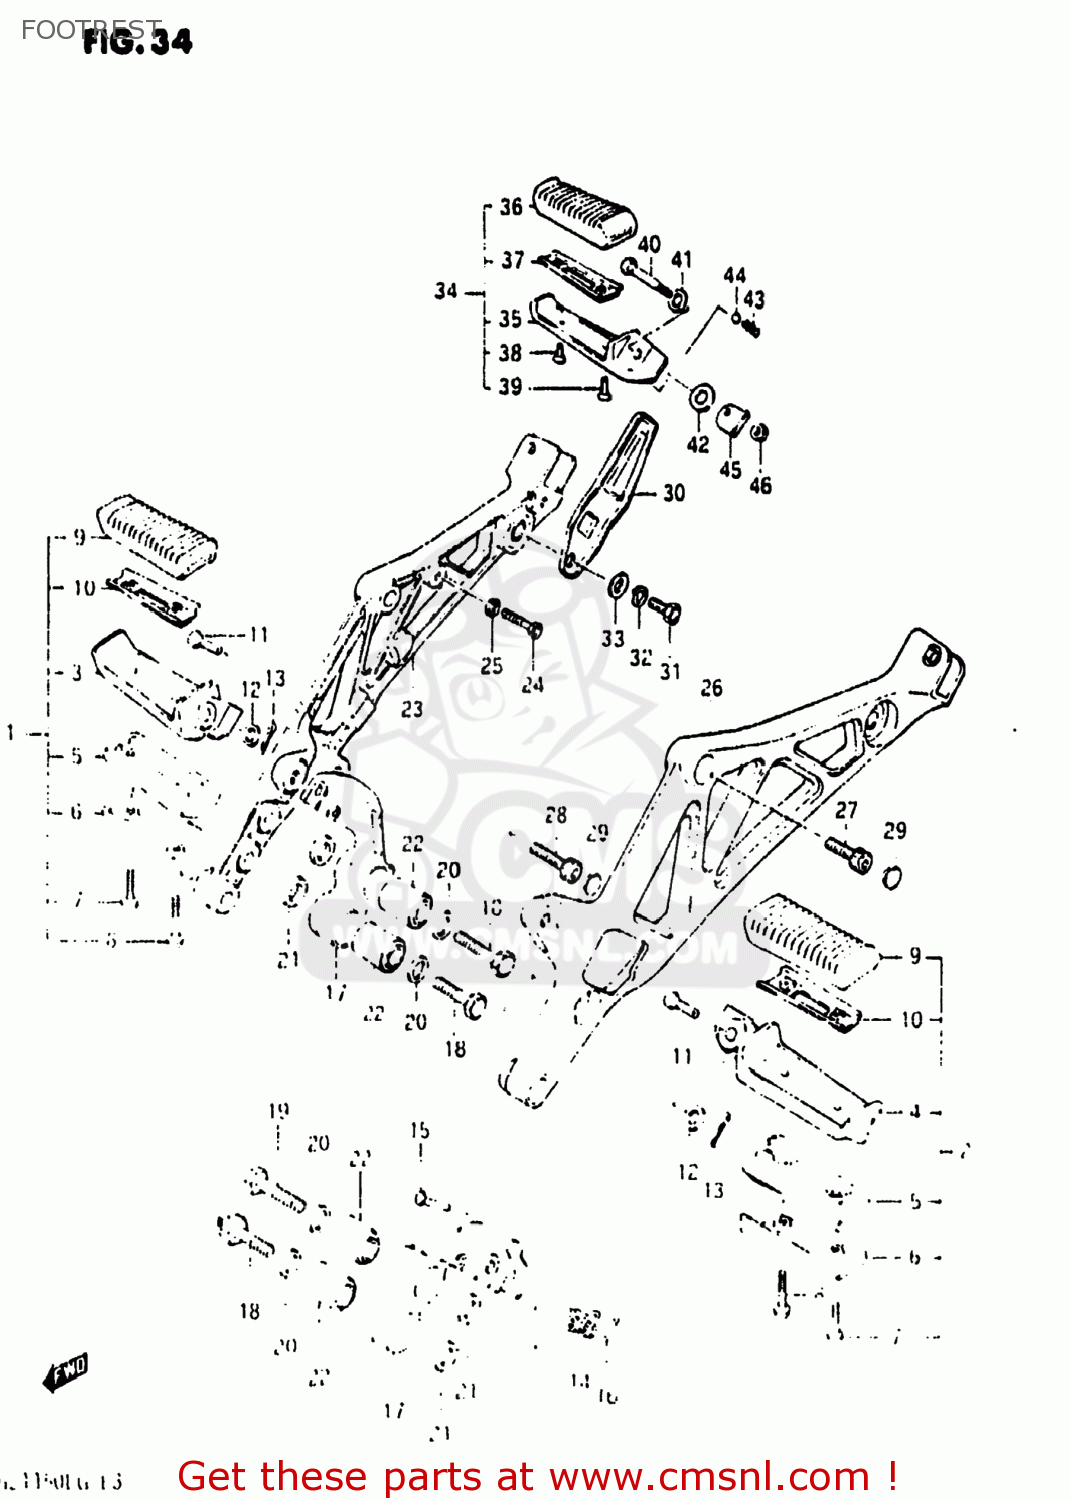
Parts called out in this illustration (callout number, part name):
1	FOOTREST ASSY,FR,R
2	FOOTREST ASSEMBLY,FRONT,LEFT
3	BAR,FRONT FOOTREST,RIGHT
4	BAR,FR FOOTREST,L
5	BAR,FR FOOTREST NO.2
6	COVER,FRONT FOOTREST B
7	SCREW
8	SCREW
9	RUBBER,FOOTREST
10	PLATE,FR FOOTREST RUBBER
11	PIN
12	WASHER
13	PIN 20X20
14	SPRING
15	PIN
16	PIN 20X20
17	HOLDER,FRONT FOOTREST
18	BOLT 10X40
19	BOLT
20	WASHER
21	WASHER(10.5X20X3.2)
22	BUSHING
23	BRACKET,MUFFLER,RIGHT
24	BOLT
25	NUT 6MM
26	BRACKET,MUFFLER,LEFT
27	BOLT
28	BOLT, CENTER
29	CAP
30	GUIDE,REAR FOOT
31	BOLT 8X12
32	LOCK WASHER
33	WASHER
34	FOOTREST ASSY,PILLION,R
35	BAR,PILLION FOOTREST,LEFT
36	RUBBER,RR FOOTREST
37	PLATE,RUBBER STOPPER
38	SCREW 5X12
39	SCREW 5X16
40	BOLT
41	WASHER
42	SHIM(8.2X22X0.2)
43	SPRING
44	BALL
45	PLATE,SPRING STOP,R
46	NUT
